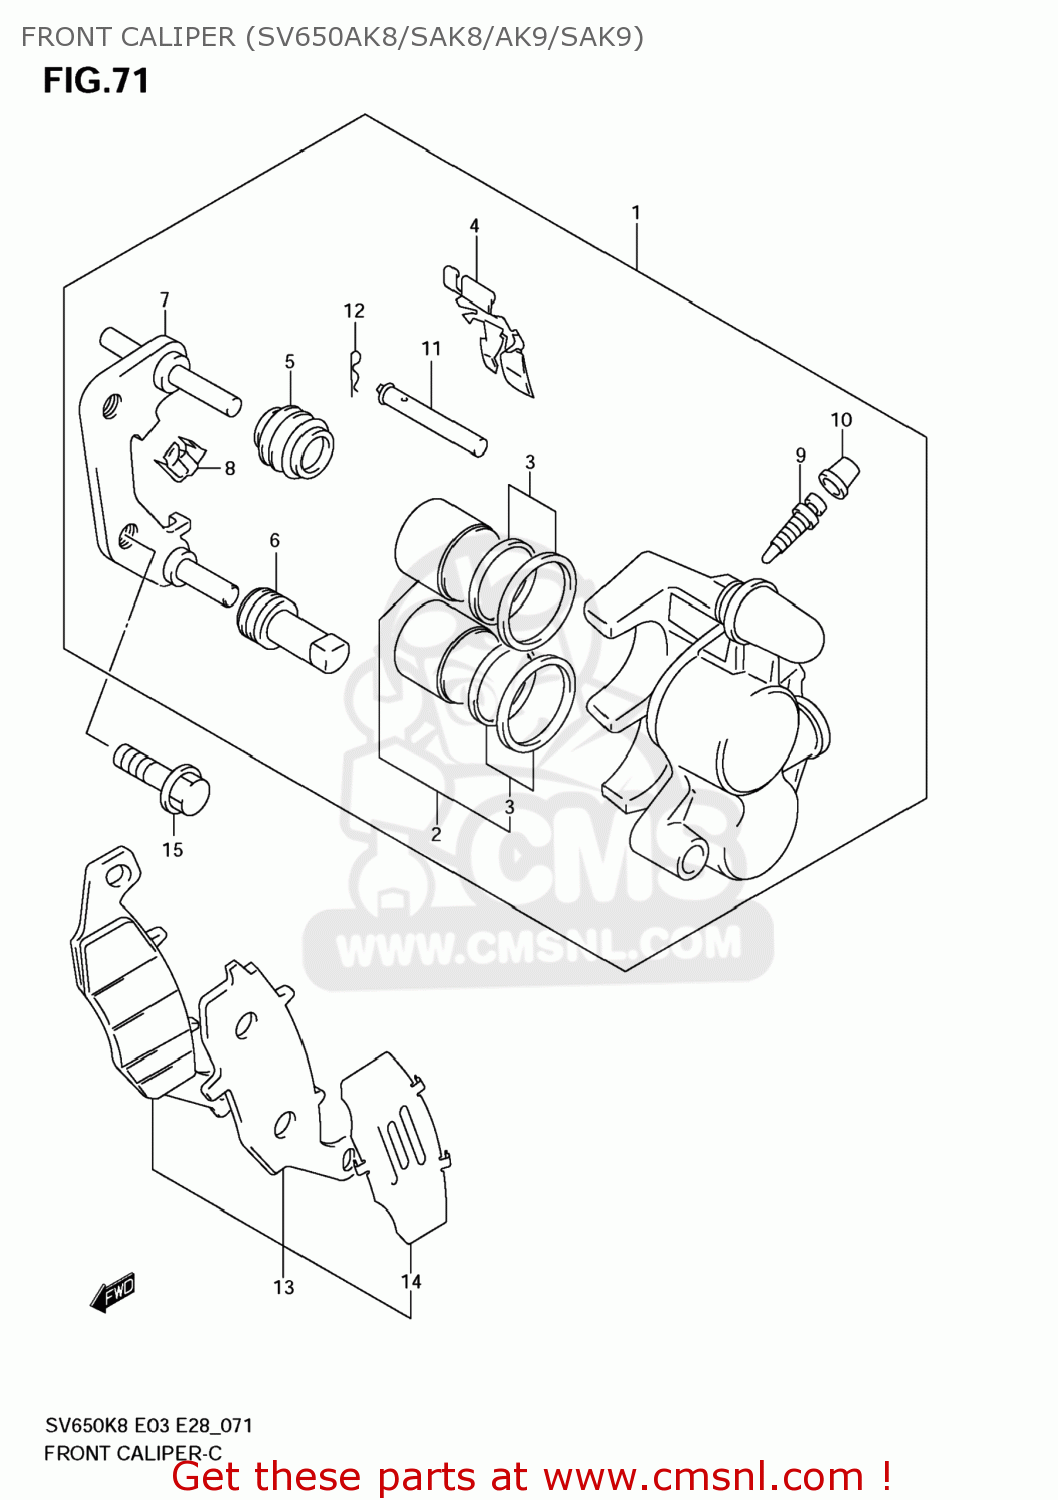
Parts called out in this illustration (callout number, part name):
1	CALIPER ASSY,FR,R
2	PISTON SET
3	SEAL SET,PISTON
4	SPRING,PAD,R
5	BOOT,AXLE
6	INSULATOR,AXLE
7	CARRIER,CALIPER,R
8	GUIDE,PAD
9	BLEEDER
10	CAP,BLEEDER PLUG
11	PIN,PAD
12	CLIP,PAD PIN
13	PAD & SHIM SET (NAS)
14	SHIM,PAD
15	BOLT
